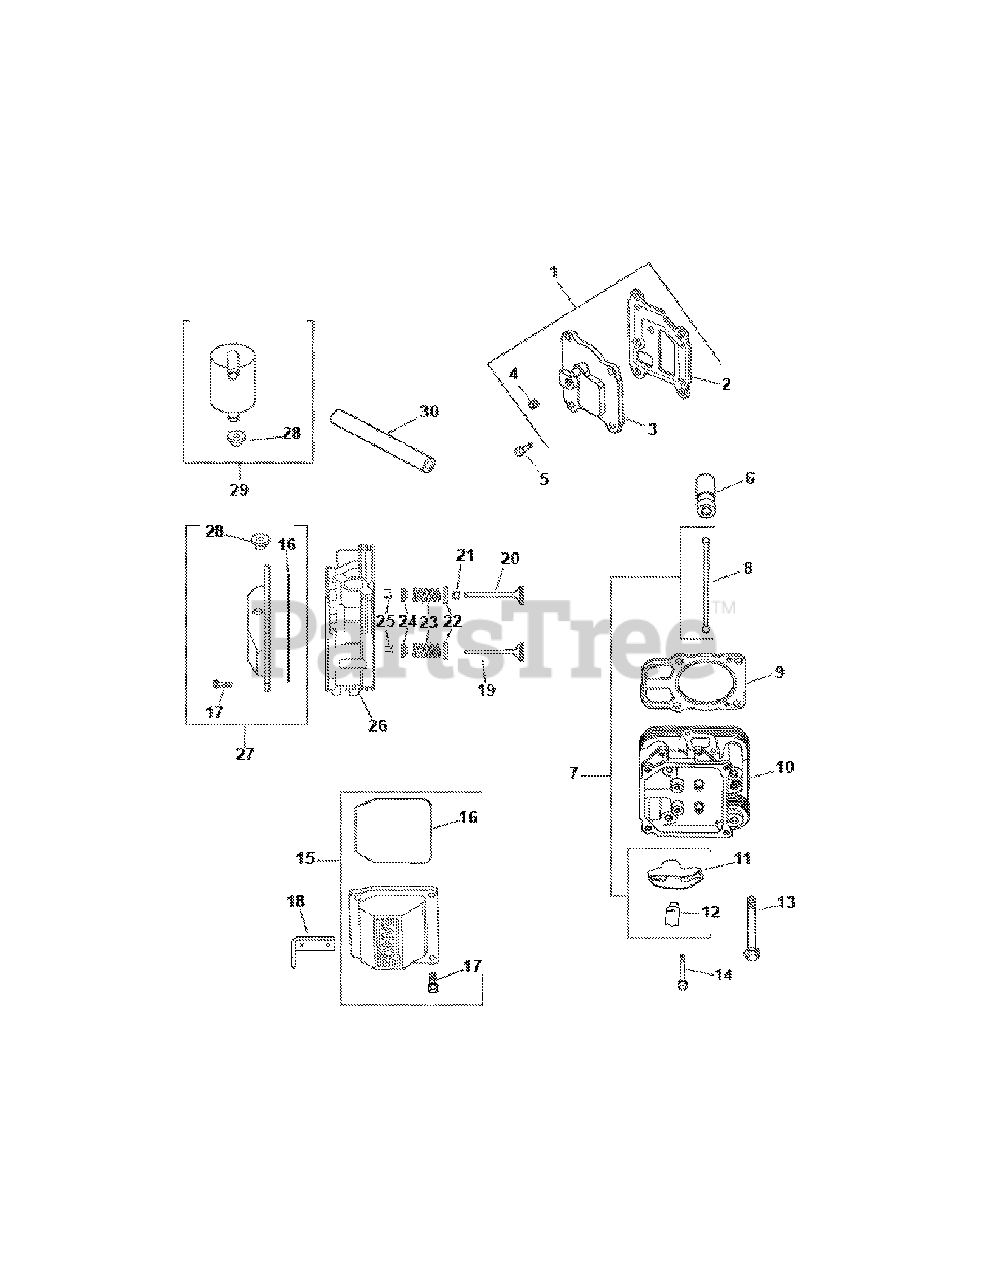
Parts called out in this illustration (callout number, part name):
1	Breather Cover Kit
2	Breather Gasket
3	Breather Cover
4	1/8" Pipe Plug
5	Hex Flange Screw
6	Valve Lifter
7	Valve TrainKit
9	Cylinder Head Gasket
10	Cylinder Head Assembly #2
12	Rocker Arm Pivot
13	Hex Flange Screw
14	Rocker Arm Pivot Screw
15	Rocker Cover Kit
16	O-Ring
17	Hex Flange Screw
18	Lifting Strap
19	Exhaust Valve
20	Intake Valve
21	Valve Stem Seal
23	Valve Spring
24	Valve Spring Retainer
25	Retainer Kit
26	Cylinder Head Assembly #1
27	Rocker Cover (Separator) Kit
28	Rubber Grommet
29	Breather Separator Kit
30	Breather Hose
